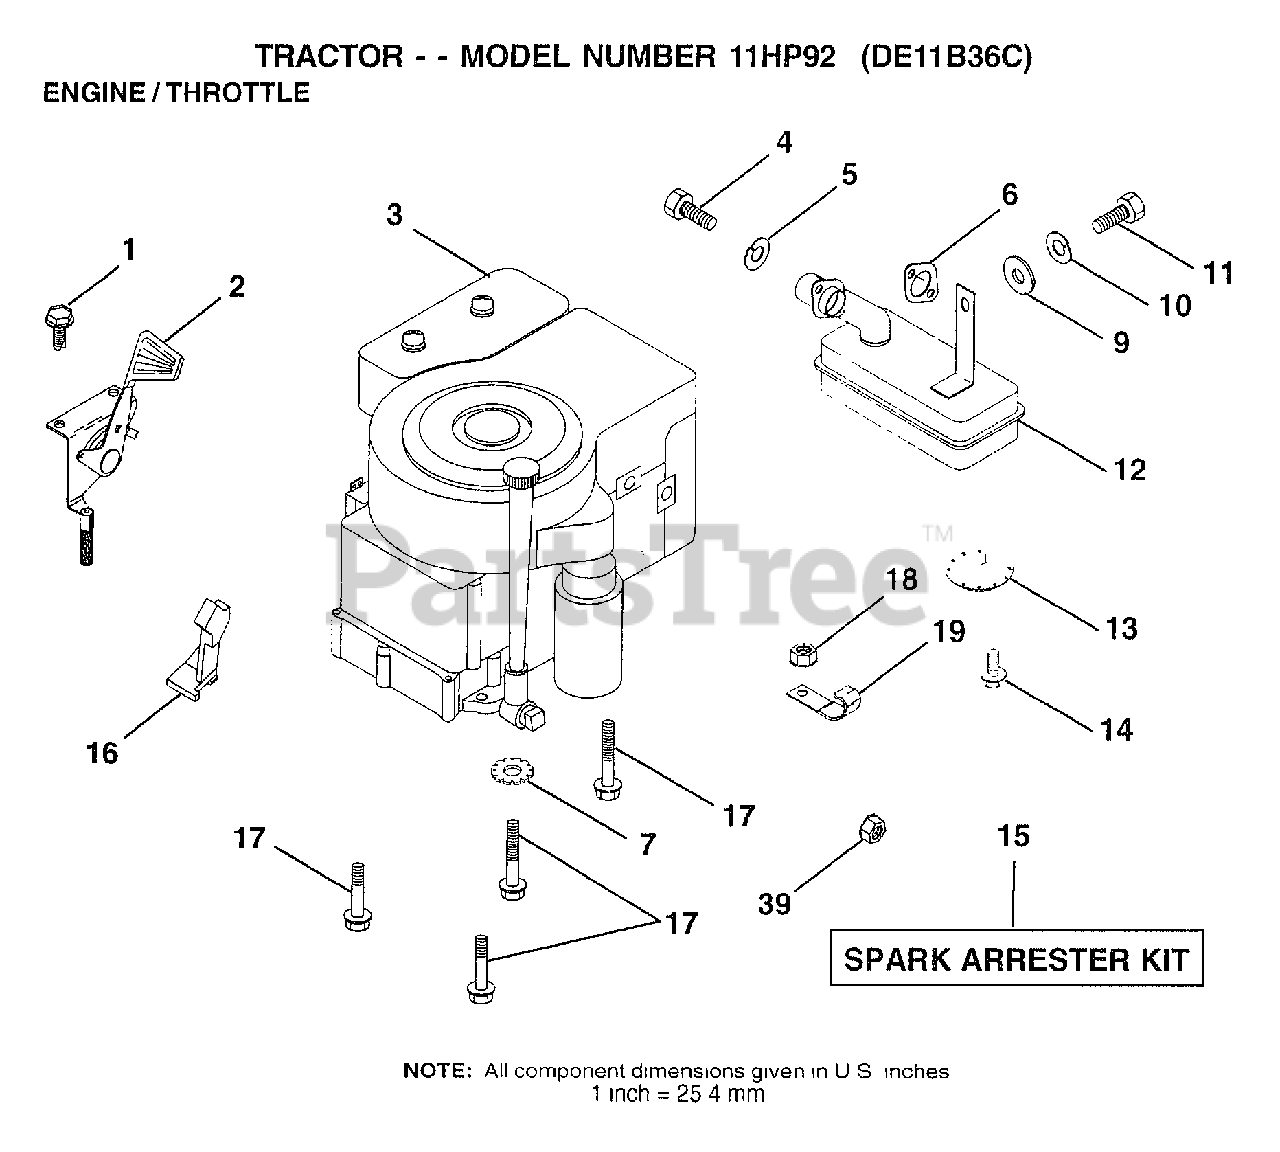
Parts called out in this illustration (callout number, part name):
1	SCREW LT
4	SCREW
5	LOCKWASHER
7	LOCKWASHER
8	BOLT T
10	LOCKWASHER
12	MUFFLER
13	DEFLECTOR.222573
16	"STOP,DASH THROTT"
17	SCREW LT
39	NUT
